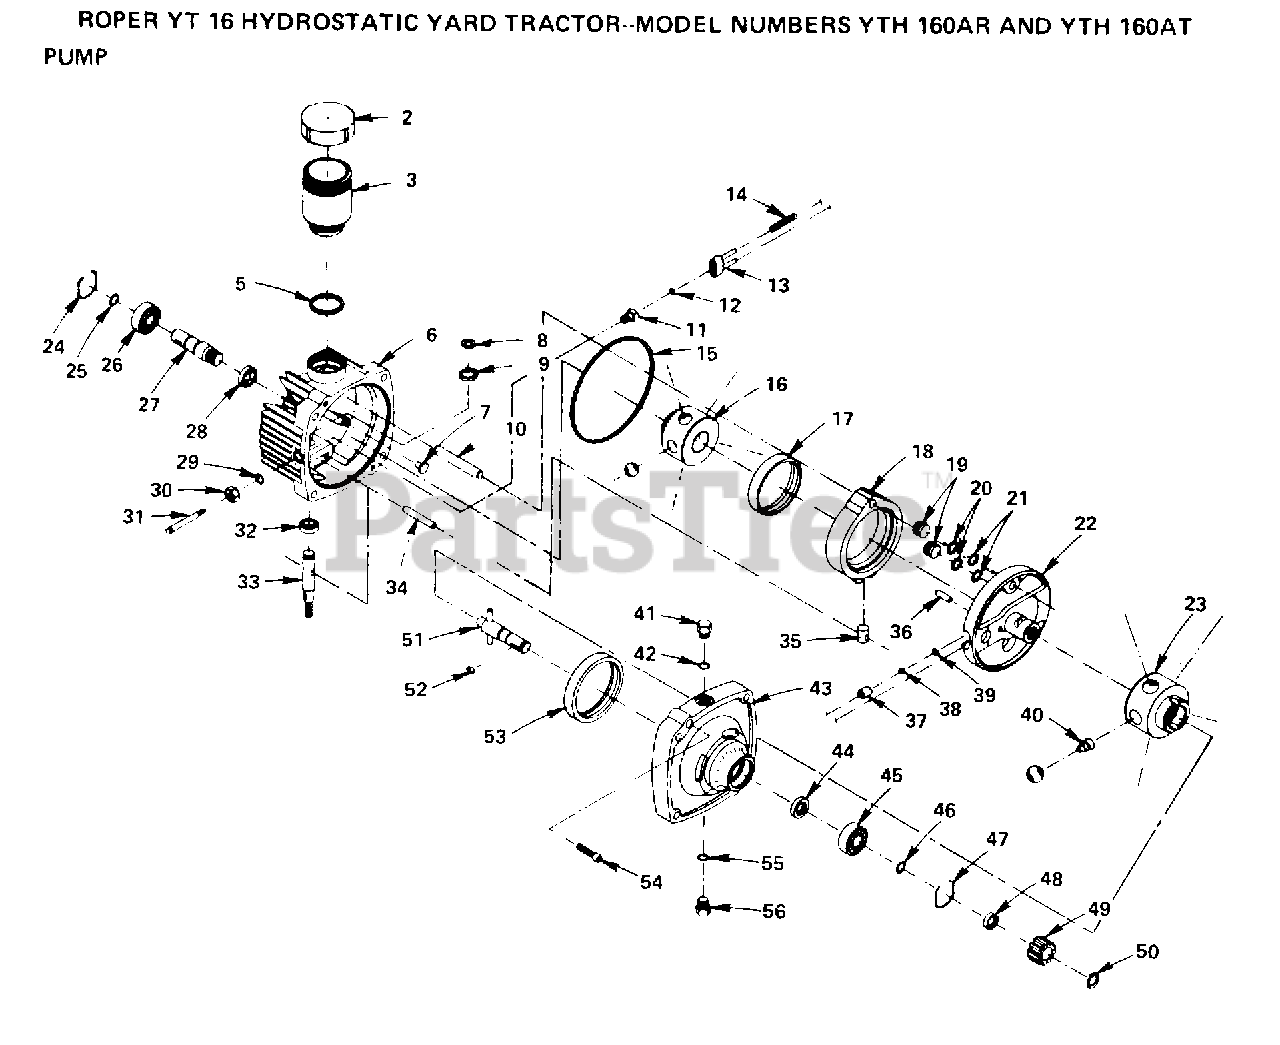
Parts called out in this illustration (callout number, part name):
1	KNOB T(3/8 HOLE)
2	ROD COAST HYT
3	NUT
4	TRUNION HYT
5	SPRING.RETAINER
6	CONTROL COAST HYT
7	BRKT ASSEM HYT
8	BOLT - HEX 3/8 - 16 X 3
9	BOLT
10	LOCKWASHER
11	WASHER
12	FAN HYDRO HYT
18	KEY T
19	PUMP HYDRO HYT
20	GASKET HYDRO HYT
23	WASHER
